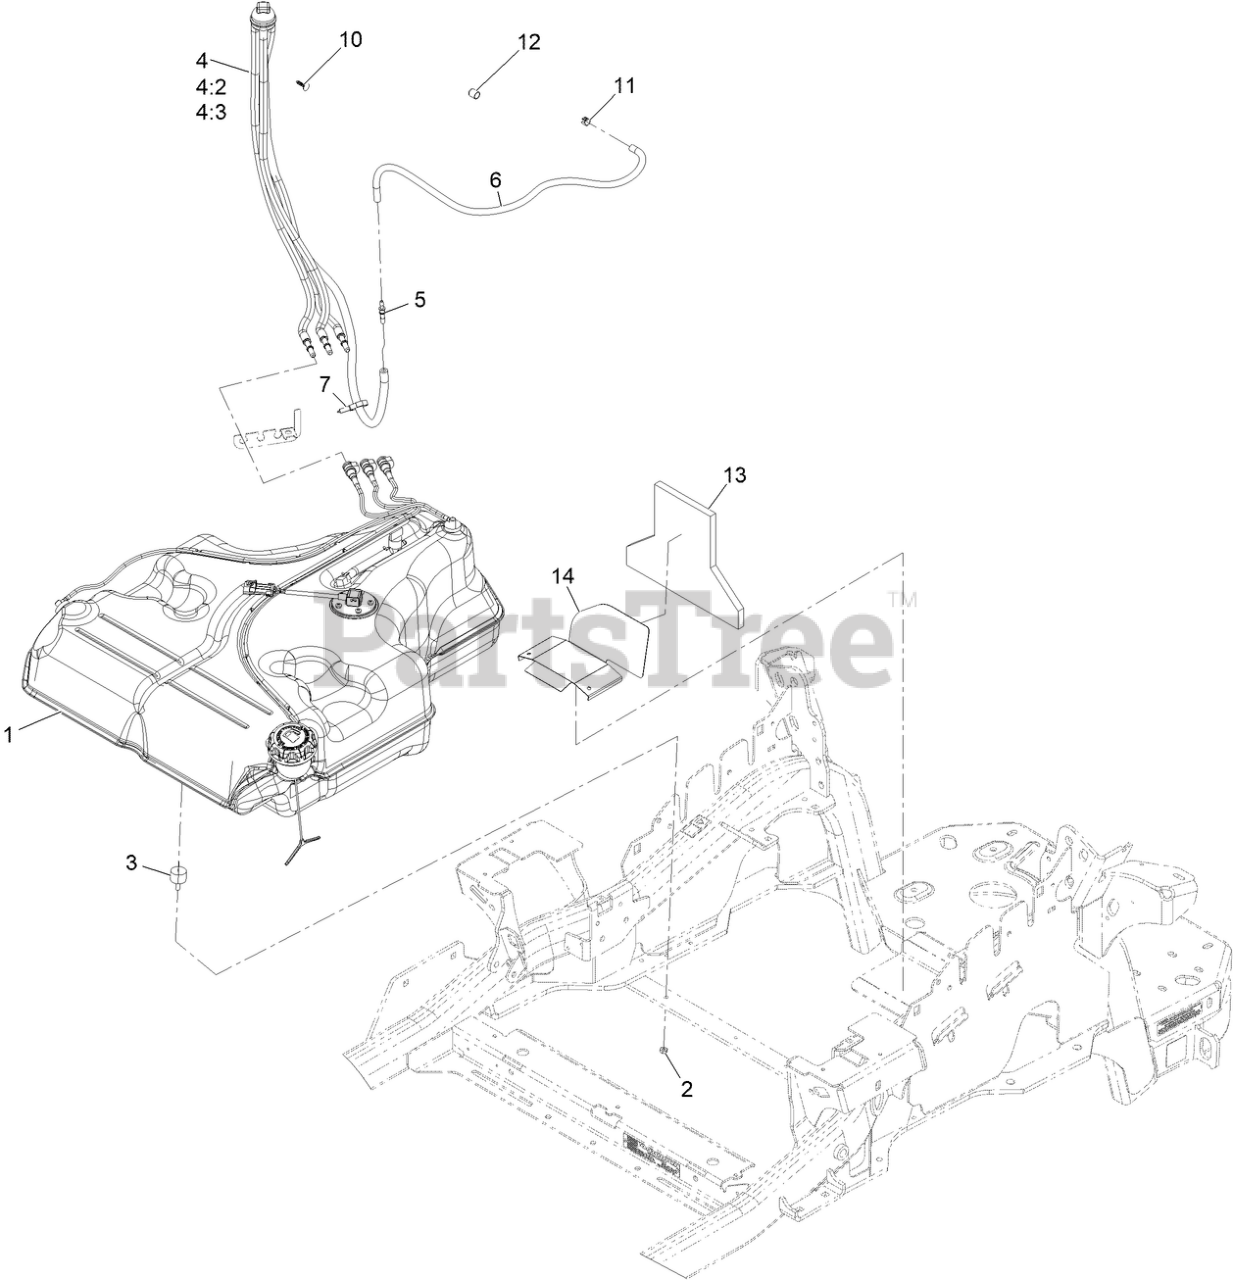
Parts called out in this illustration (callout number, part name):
1	FUEL TANK ASM
2	NUT-JAM
4	FUEL MANIFOLD VENT ASM
4:2	HOSE-FUEL
4:3	HOSE-FUEL
5	BARB-FUEL
6	Hose-Fuel
7	CLAMP-HOSE
10	PLUG-PLASTIC
11	CLAMP-HOSE
12	PLUG-PORT
13	INSULATION-FOAM, FUEL TANK
14	GUARD-EXHAUST
